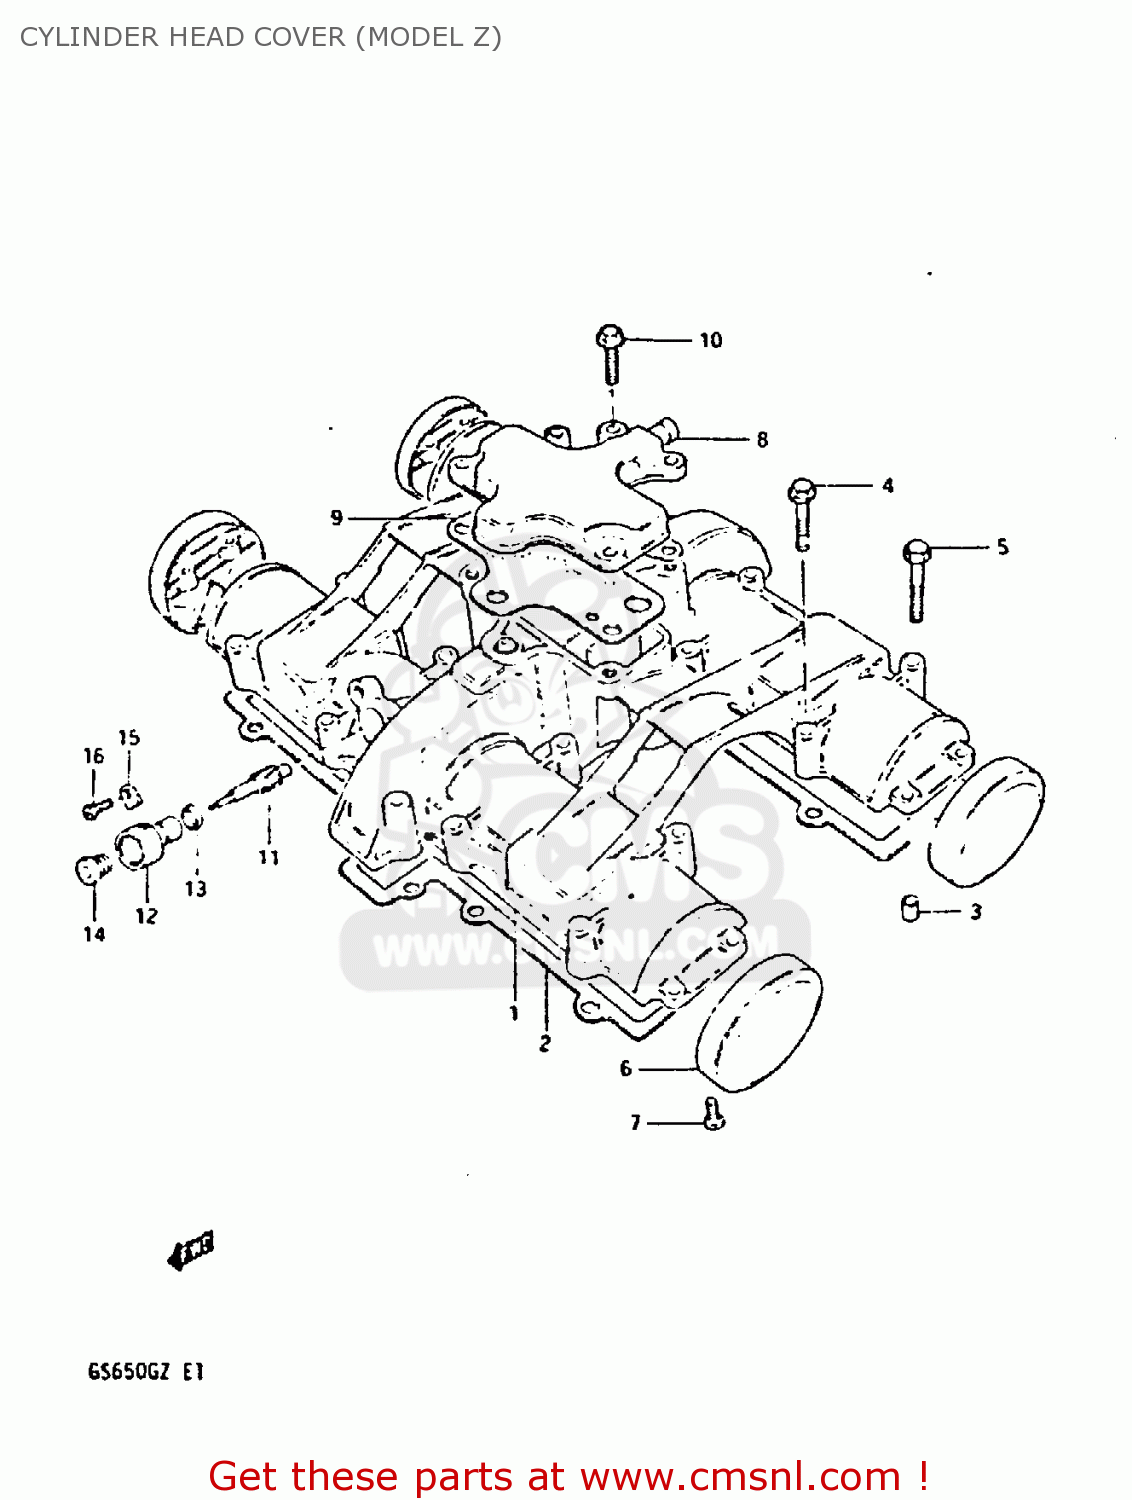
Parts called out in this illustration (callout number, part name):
1	COVER,CYLINDER HEAD
2	GASKET,CYLINDER HEAD COVER (MCA)
3	PIN(6.2X8X11)
4	BOLT
5	BOLT,UNDER
6	CAP,CYLINDER HEAD COVER
7	SCREW
8	COVER,BREATHER
9	GASKET (MCA)
10	BOLT,REAR
11	GEAR,TACHOMETER DRIVEN
12	SLEEVE,TACHOMETER DRIVE
13	SEAL,TACHOMETER DRIVEN
14	SEAL,OIL(5X12X8)
15	PLATE,TACH DRIVE GEAR SLEEVE
16	SCREW(5X12)
